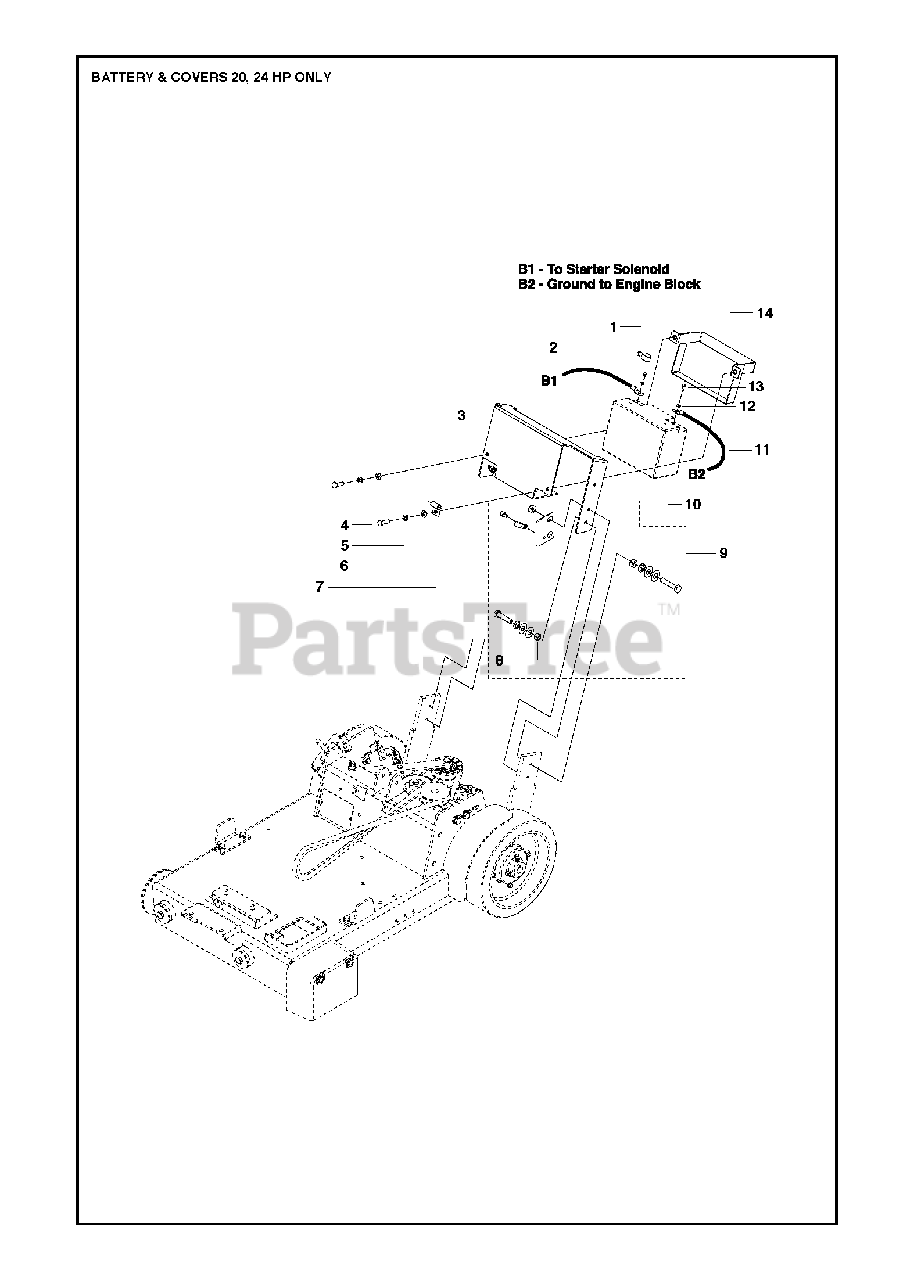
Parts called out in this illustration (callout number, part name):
5	SPRING WASHER
6	WASHER
8	HEXAGON LOCKING NUT
